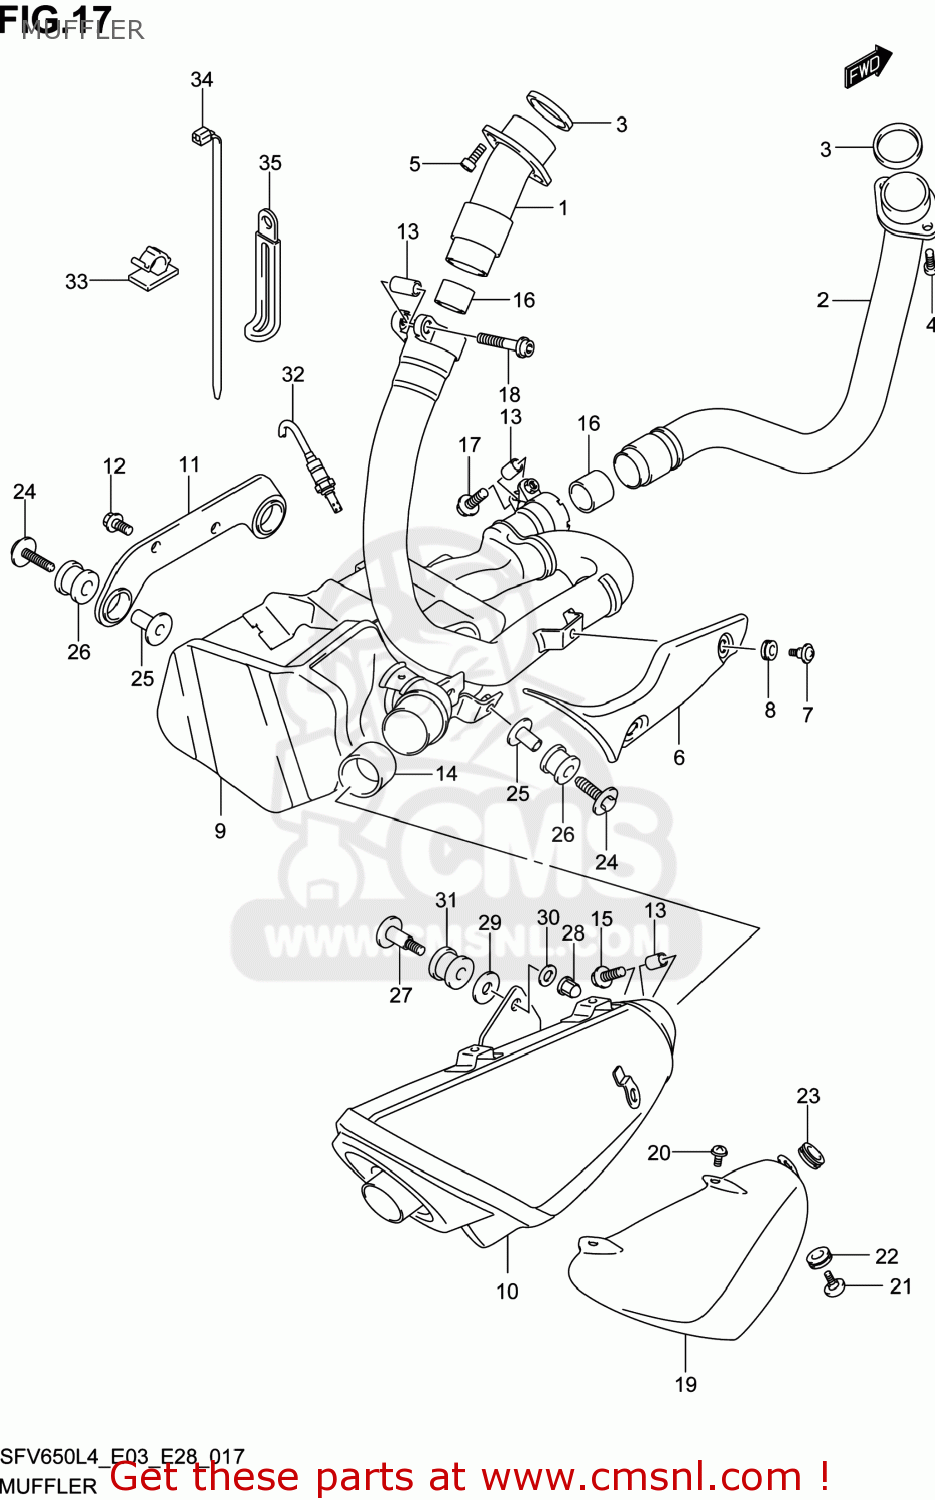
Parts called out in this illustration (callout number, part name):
1	PIPE,EXHAUST RR
2	PIPE,EXHAUST FR
3	GASKET,EXHAUST PIPE (NAS)
4	BOLT(8X25)
5	BOLT
6	COVER,EXHAUST
7	SCREW(6X12)
8	CUSHION
9	CHAMBER
10	BODY,MUFFLER
11	BRACKET,MUFFLER SUPPORT
12	BOLT
13	SPACER,MUFFLER
14	CONNECTOR,MUFFLER
15	BOLT(8X35)
16	CONNECTOR,MUFFLER
17	BOLT(8X35)
18	BOLT(8X40)
19	COVER,MUFFLER
20	SCREW(6X10)
21	SCREW(6X12)
22	CUSHION
23	CUSHION
24	BOLT(8X40)
25	SPACER(8.6X12X24.2)
26	CUSHION
27	BOLT,MUF SPRT RR
28	NUT
29	WASHER(8.5X30X2.3)
30	WASHER(8.5X20X1.6)
31	CUSHION
32	SENSOR,OXYGEN
33	CLIP
34	CLAMP(L:165)
35	CLAMP(L:45)
